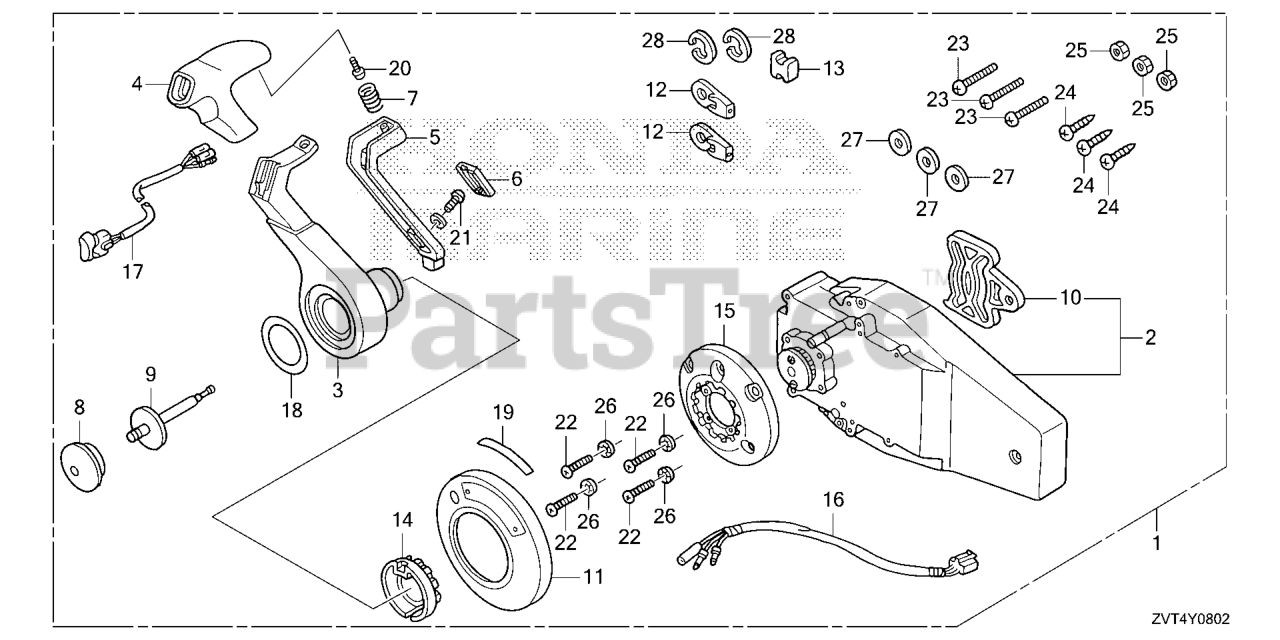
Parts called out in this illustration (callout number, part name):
1	BOX KIT, R. REMOTE CONTROL (FLUSH MOUNT)
2	HOUSING ASSY., R. (INNER) (FLUSH MOUNT)
3	HANDLE, REMOTE CONTROL
4	COVER, GRIP
5	ARM, NEUTRAL LOCK
6	COVER, LOCK ARM
7	SPRING, NEUTRAL LOCK ARM
8	BUTTON, THROTTLE
9	SHAFT, THROTTLE BUTTON
10	PLATE, DWELL
11	COVER ASSY.
12	TERMINAL, CABLE
13	SPACER, CABLE CLAMP
14	HOLDER, NEUTRAL LOCK
15	BASE
16	SUB-HARNESS ASSY., POWER TRIM-TILT (C)
17	SWITCH ASSY., POWER TRIM-TILT (C)
18	MARK, HANDLE FLUSH MOUNT
19	MARK, FLUSH MOUNT
20	SCREW, PAN (5X16)
21	SCREW, TRUSS (4X12)
22	SCREW, PAN (5X30)
23	SCREW, PAN (6X35)
24	SCREW, TAPPING (6X30)
25	NUT, HEX. (6MM)
26	WASHER, LOCK (5MM)
27	WASHER, PLAIN (6MM)
28	E-RING (6MM)
